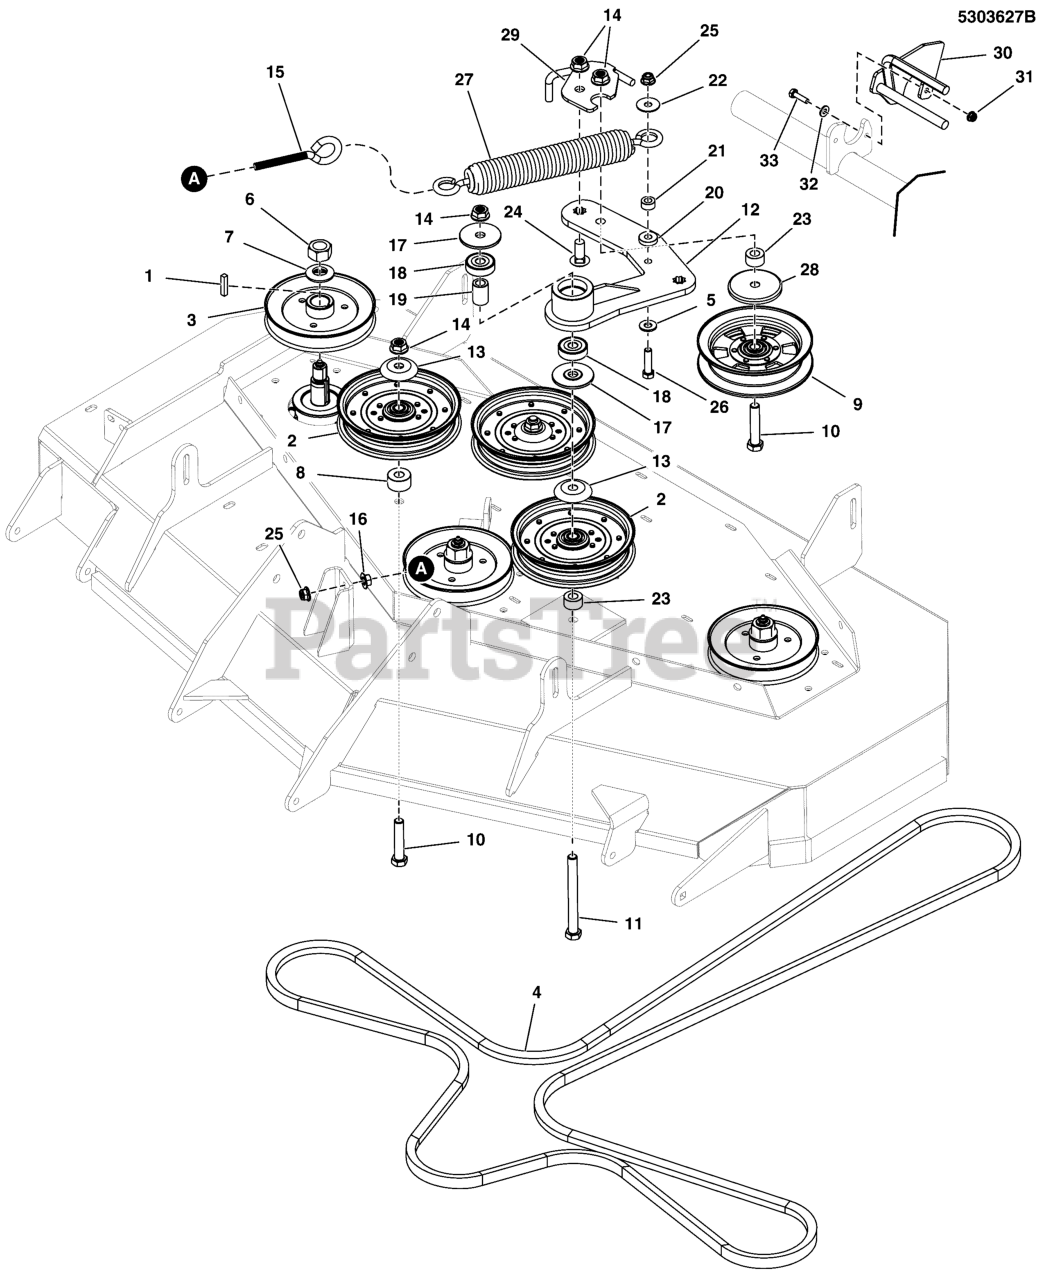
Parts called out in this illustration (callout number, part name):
1	KEY, 1/4 SQ X 1-1/4
3	PULLEY, 5.926OB X .985ID, SINGLE B-SEC
4	BELT, 5V, 163.40"EL, LG ARAMID WRPD, RC
5	WASHER, 1/2 SAE
6	NUT, 3/4-16 HEX
7	WASHER, 3/4 BELLEVILLE CL/ZC
8	SPACER, .52 X 1.25 X .70, PM, CZ
9	PULLEY,IDLER,BACKSIDE,NOSEAM 6.25ODX.5ID
10	BOLT, 1/2-13 X 2-1/2" GD5 CZ
11	BOLT-1/2-13 X 5 GD5 CZ
13	SHIELD, PULLEY BEARING, CZ
14	NUT, Hex Flange, Nylock, 1/2-13
15	EYE BOLT, 3/8-16 X 5, 2.88THRD, 1EYE, CZ
16	NUT, 3/8-16 HEX SERRATED FLANGE
17	SPACER, IDLER ARM, 1/2 X 2.25
18	BEARING, 6203-1/2", SEALED
19	SPACER, .51 X .84 X 1.22, PM, CZ
20	SPACER, .39 X 1.00 X .25, PM, CZ
21	SPACER, .39 X .75 X .38, PM, CZ
22	WASHER-3/8 FENDER
23	SPACER, .52 X 1.00 X .56, PM, CZ
24	BOLT, CARRIAGE 1/2-13 X 1-1/4 GD.5
25	NUT, 3/8-16 HEX NYLOCK FLANGE
26	BOLT, 3/8-16 X 1-1/2" GD5 CZ
27	SPRING, EXT, 1.5ODX12.25X.234WIRE BLK
28	SHIELD, BEARING, 1/2 ID X 2-7/8 OD, CZ
29	WELD, BELT GUIDE - BLK
30	WELD, CLUTCH BELT GUIDE
31	NUT, 1/4-20 HEX NYLOCK FLANGE
32	WASHER, 1/4 SAE
33	BOLT, 1/4-20 X 1" GD5 CZ
